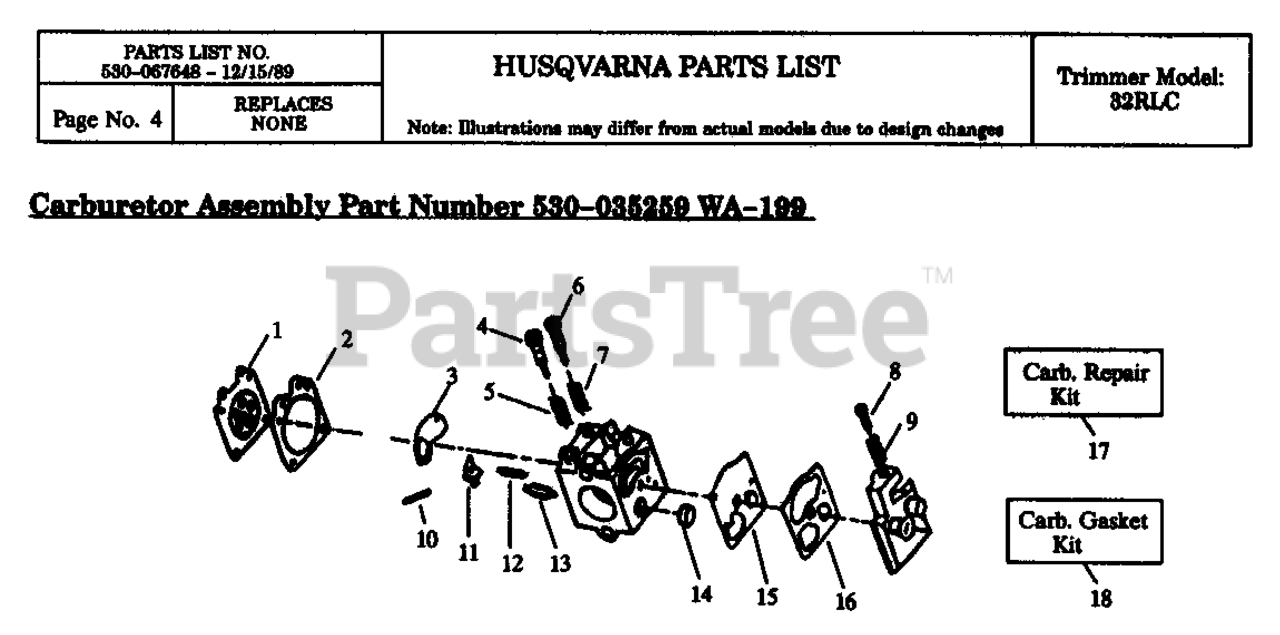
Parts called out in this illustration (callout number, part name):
1	DIAPHRAGM
2	GASKET-METER DIAP
3	GASKET-CIRCUIT PLATE
4	HI-SPEED NEEDLE
5	Hi Speed Needle Spring
6	NEEDLE - IDLE
7	SPRING-NEEDLE FUEL MIX
8	SCREW-IDLE SPEED
9	SPRING-IDLE SPEED
10	PIN
11	LEVER
12	SPRING-METERING LEVER
13	INLET NEEDLEVALVE
14	SCREEN-DUTCH TWILL INLE
15	DIAP FUEL PUMP
16	GASKET-FUEL PUMP
17	REPAIR KIT
18	KIT-KWIK REPAIR
